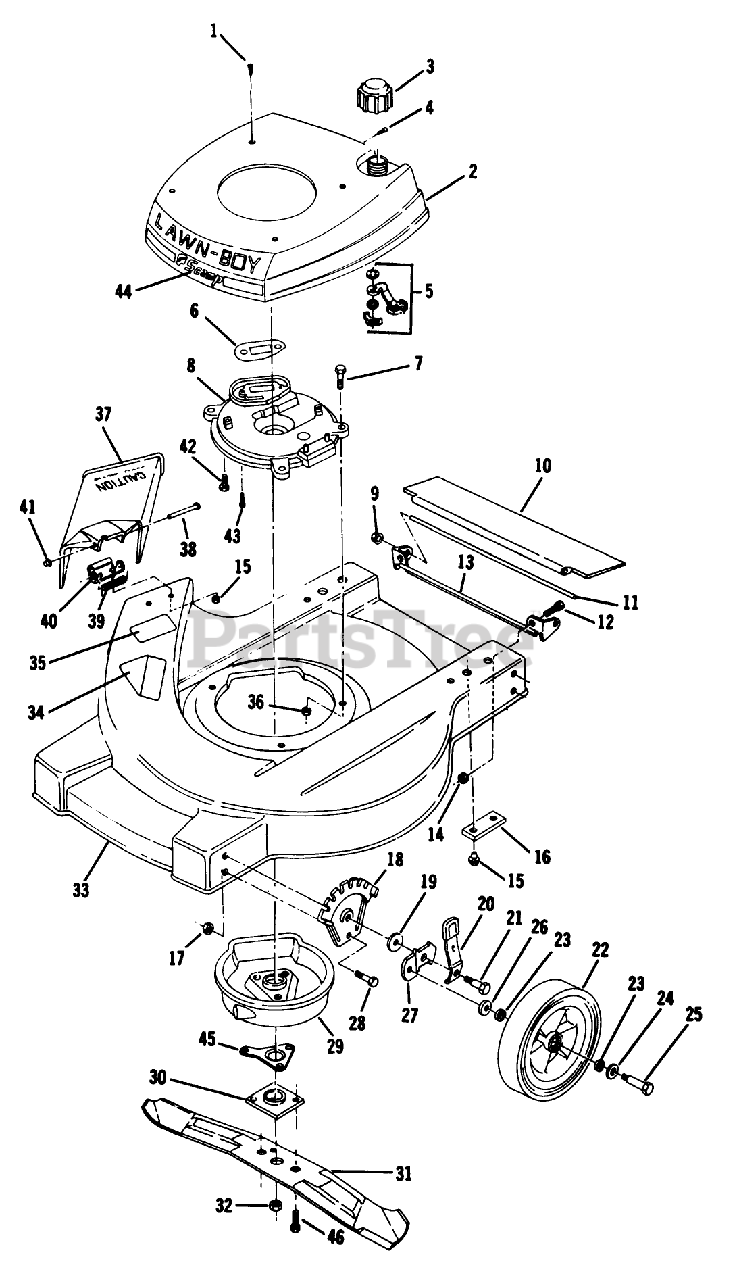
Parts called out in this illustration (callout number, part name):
1	SCREW LAWRENCE
3	FUEL CAP & INSERT
4	SCREW S
8	PLATE,MUFFLER F
10	TRAILING SHIELD
13	BRACKET (12)
14	LOCKNUT E
17	LOCKNUT
20	KNOB & SPRING
25	BOLT WHEEL
26	WASHER WROUGHT
30	PLATE AND COLLAR ASM
32	NUT-BLADE
36	NUT-LOCK F
37	CHUTE DEFLECTOR AY
40	HINGE & SCREW ATA
43	SCREW V
45	SUPPORT F
